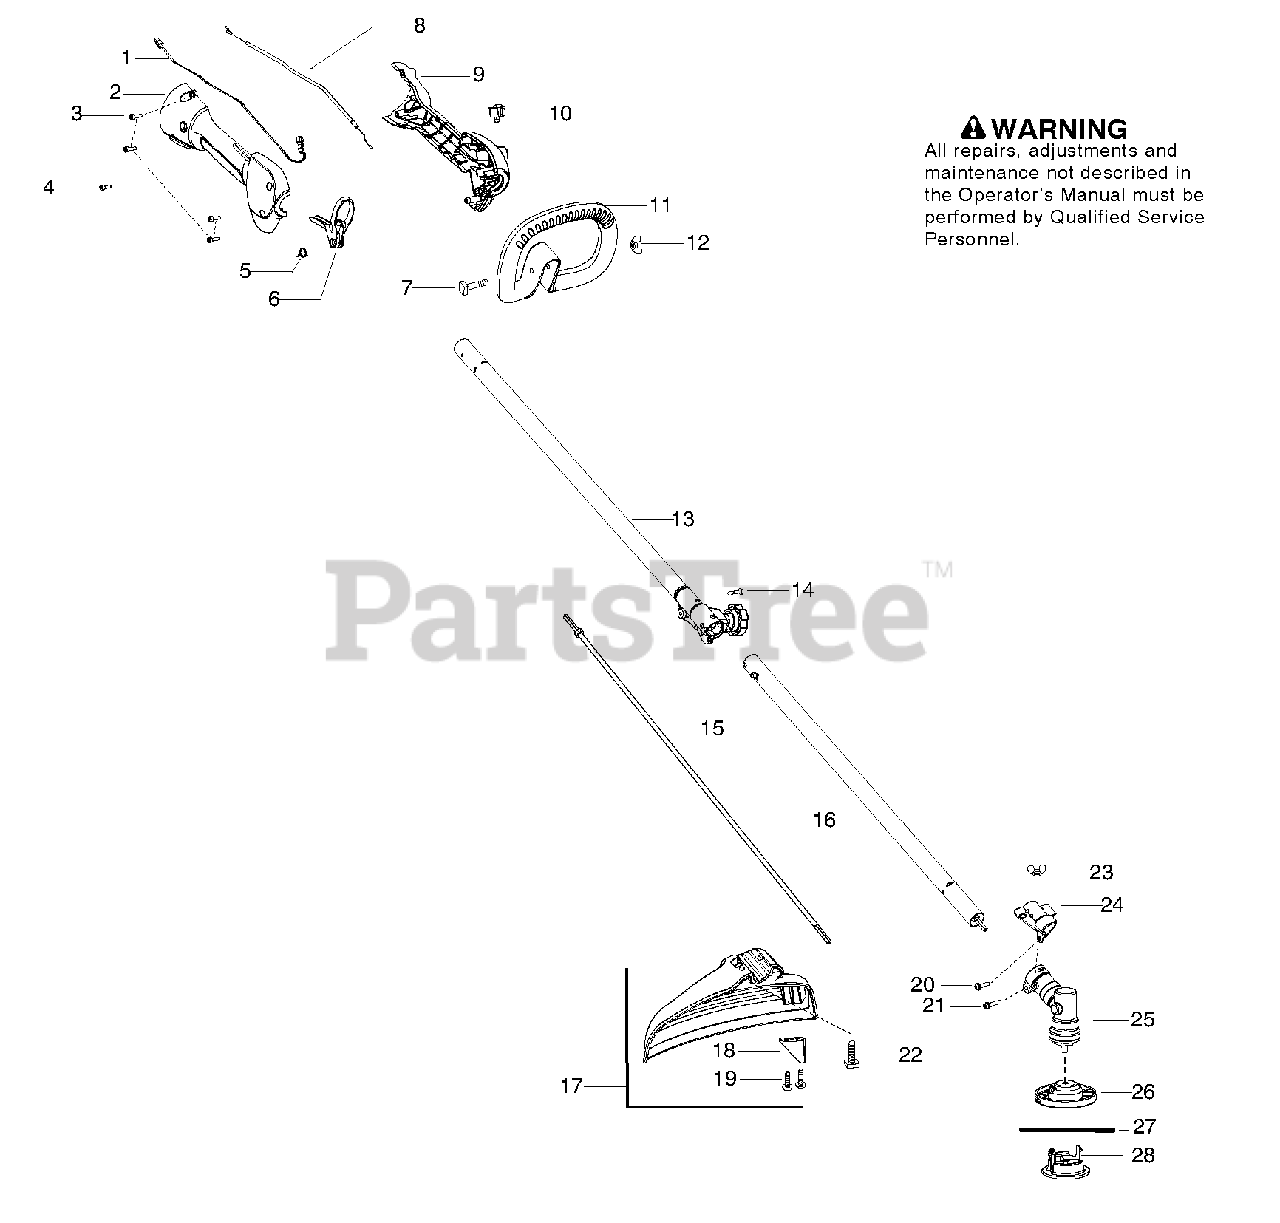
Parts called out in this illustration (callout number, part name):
1	Assy-Switch Wire
2	Housing-Throttle (RH)
4	Screw 10 -14 x1/2
5	Spring-Trigger
6	Kit - Trigger
7	Bolt -1/4 -20 x 2
8	Assy -Throttle Cable
9	Housing-Throttle (LH)
10	Kit-Switch
11	Assy - Handle Assist
12	Wingnut -1/4 - 20
13	Kit-Driveshaft Upper (Incl. #14)
14	Screw -12 - 24 x .480
16	Kit-Driveshaft Lower
17	Kit-Shield
19	Screw -10 - 14 x 3/4
20	Screw - 8-16 x .593
21	Screw - 12-24 x .960
22	Bolt - 1/4-20 x 1-1/4
23	Wingnut - 1/4-20
24	Bracket - Shield
25	Assy - Gearbox 1"
26	Assy - Fixed Line Head
27	Accy - Line (12 pcs )
28	Cap - Fixed Line
